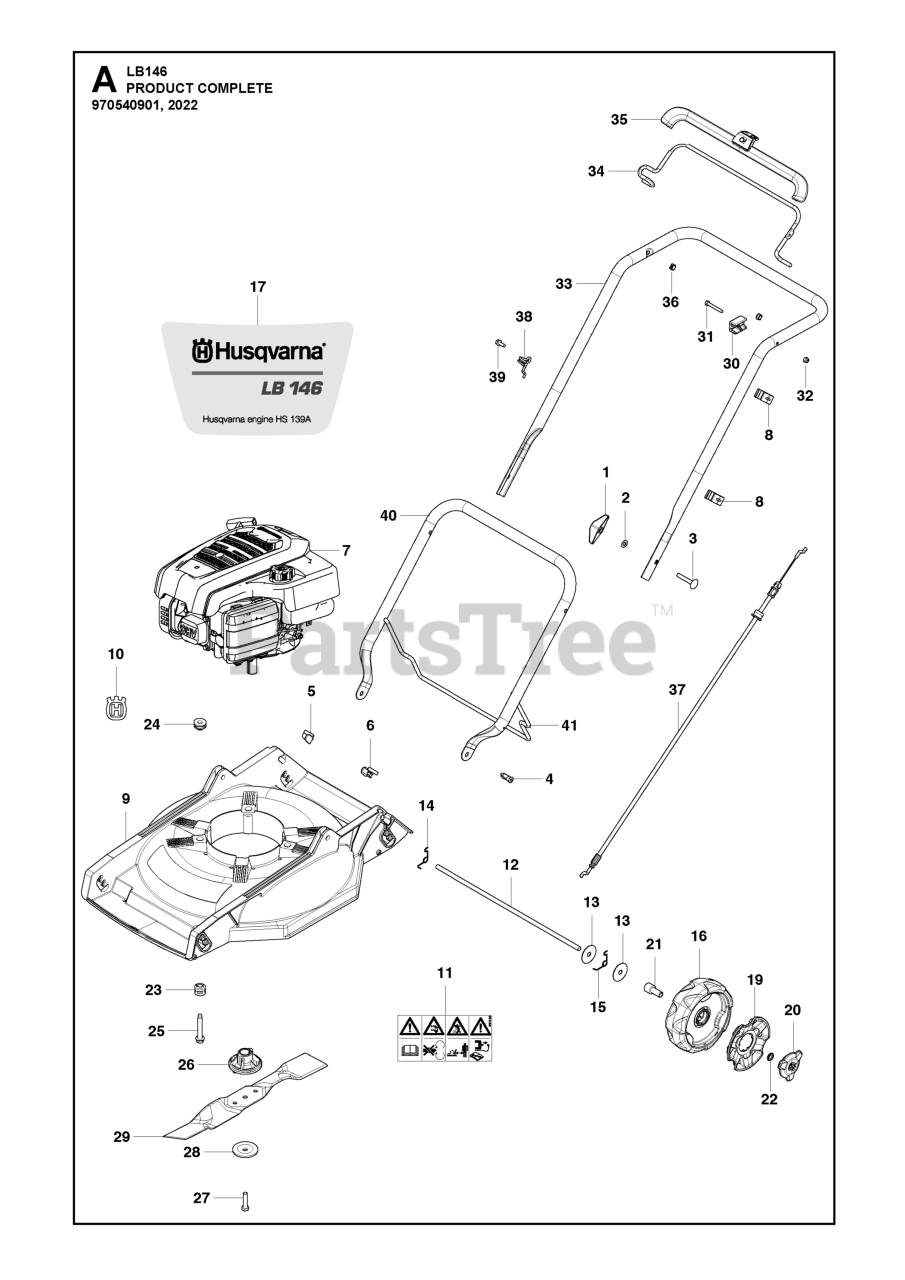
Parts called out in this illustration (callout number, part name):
1	WINGNUT
10	DECAL HUSQVARNA CROWN 41MM FLA
32	NUT FLANGE - M6
39	SCREW
